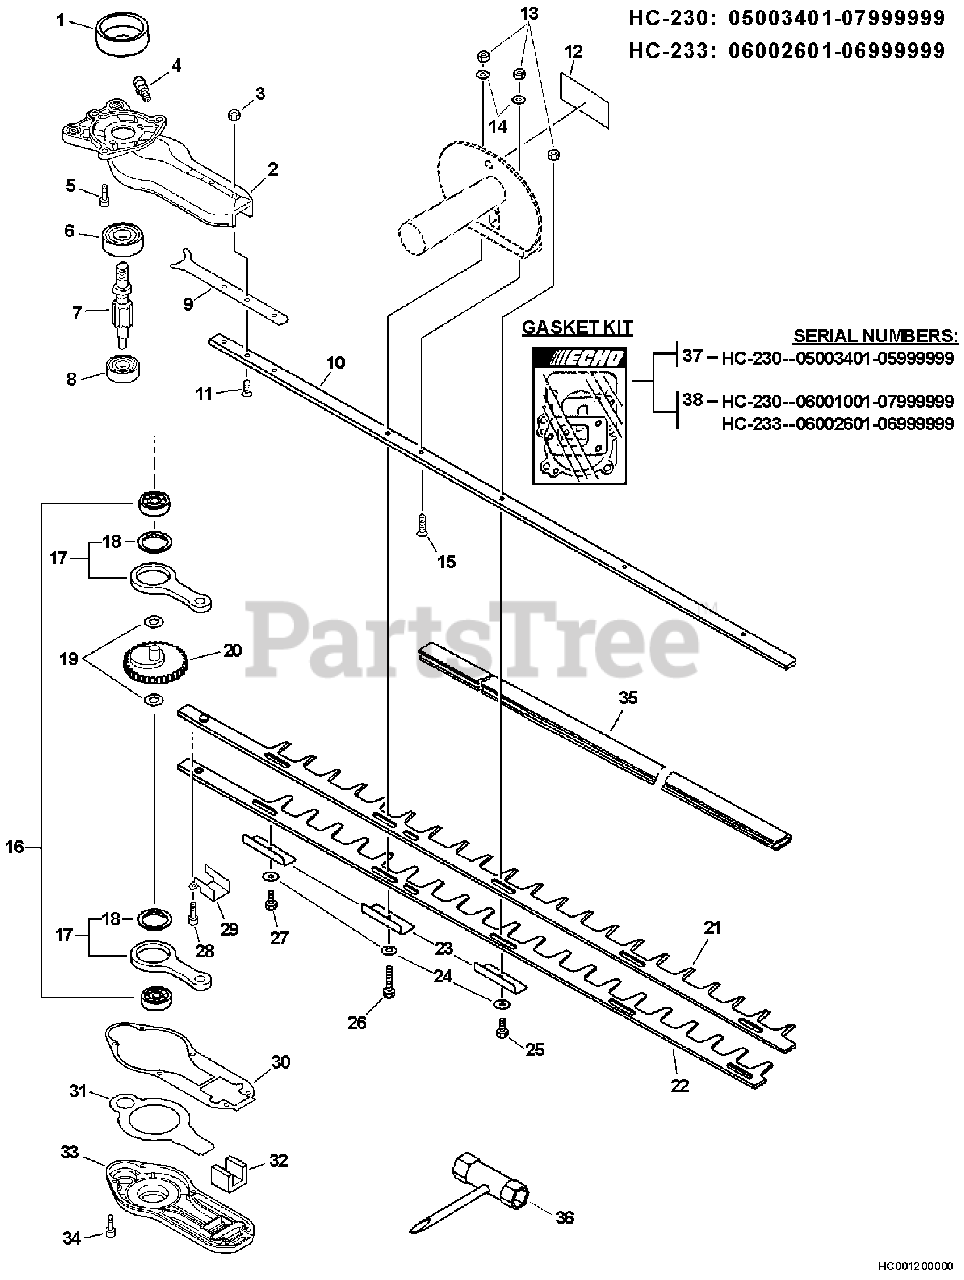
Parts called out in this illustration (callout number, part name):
1	DRUM, CLUTCH
2	CASE, GEAR - UPPER
3	NUT, FLANGE M6
4	FITTING, GREASE
5	BOLT 6×18
6	BEARING, BALL 6200
7	GEAR, SPUR
8	BEARING, BALL 608ZZ
9	PLATE, EYE
10	SUPPORT, BLADE
11	BOLT 6×30
12	LABEL, CAUTION
14	WASHER 6.5×13×1
15	BOLT 6×30
16	BEARING, BALL 6200
17	ROD, CONNECTING
18	BEARING, NEEDLE 30
19	WASHER, THRUST 10
20	GEAR, SPUR
21	BLADE - UPPER -- 30"
22	BLADE, TRIMMER - 30" -- LOWER
23	INSULATOR
25	BOLT 6×22
26	BOLT 6×40
27	BOLT 6×25
28	BOLT 4×16
29	GUIDE, BLADE
30	GASKET, GEAR CASE
31	PLATE, GEAR CASE
33	CASE, GEAR - LOWER
34	BOLT 4×16
35	SCABBARD
36	T-WRENCH 13×19×180
37	GASKET KIT
38	GASKET KIT
